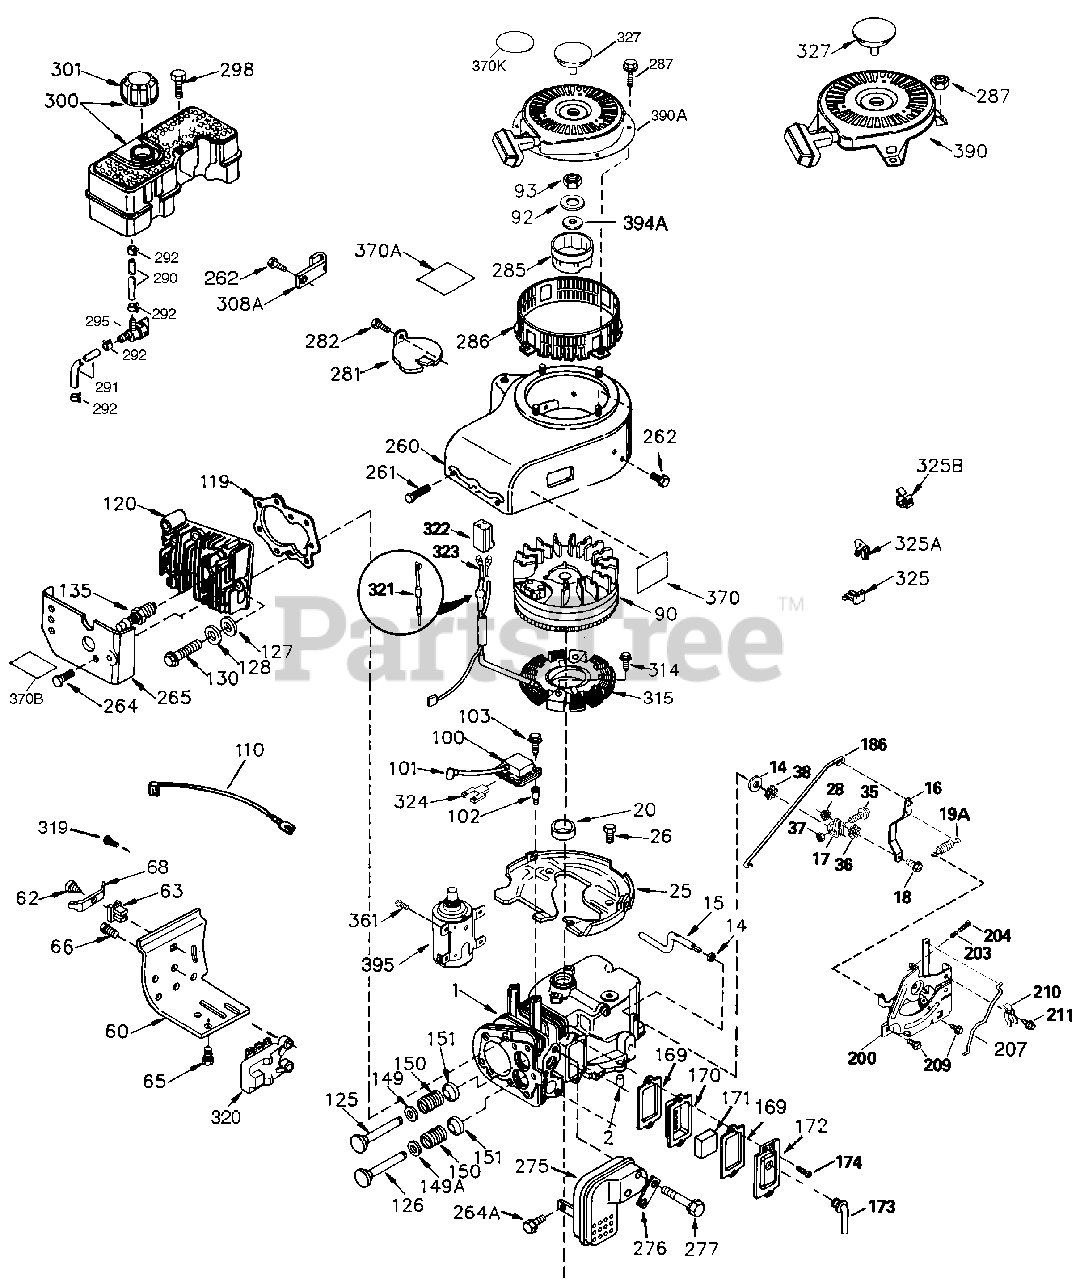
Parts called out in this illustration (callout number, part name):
1	"Cylinder (Incl. 2 & 20)
2	Dowel Pin
14	Flat Washer
15	Governor Rod
16	Governor Lever
17	Governor Lever Clamp
18	Screw, 8-32 x 5/16"
19A	Extension Spring
20	Oil Seal
25	Blower Housing Baffle (Incl. 325)
26	Screw, 1/4-20 x 5/8"
28	Lock Nut, 8-32
35	Screw, 10-32 x 3/4"
36	Lock Washer #8
37	Lock Nut, 10-32
38	Retaining Ring
60	Blower Housing Extension
64	Screw, 5/16-18 x 15/32"
65	Screw, 10-24 x 1/2"
90	Flywheel
92	Lock Washer
93	Flywheel Nut
100	Solid State Ignition
101	Spark Plug Cover
102	Solid State Mounting Stud
103	Screw, Torx T-15, 10-24 x 15/16"
110	Ground Wire
119	* Cylinder Head Gasket
120	Cylinder Head
125	Exhaust Valve (Std.)(Incl. 151)
125	Exhaust Valve (1/32" OS) (Incl. 151)
126	Intake Valve (Std.) (Incl. 151)
126	Intake Valve (1/32" OS) (Incl. 151)
128	Belleville Washer
130	Screw, 5/16-18 x 2"
135	Resistor Spark Plug - RJ17LM
149	Valve Spring Cap
149A	Valve Spring Cap
150	Valve Spring
151	Valve Spring Keeper
169	* Valve Cover Gasket
170	Breather Body
171	Breather Element
172	Valve Cover
173	Breather Tube
174	Screw, 10-24 x 1/2"
186	Governor Link
200	Control Bracket (Incl. 203,204 & 206)
203	Compression Spring
204	Screw, 5-40 x 7/16"
207	Throttle Link
209	Screw, 10-24 x 9/16"
260	Blower Housing
261	Screw, 5/16-18 x 3/4"
262	Screw, T-40, 5/16-24 x 21/32"
264A	Screw, 1/4-20 x 5/8"
265	Cylinder Head (Black)
275	Muffler
276	Locking Plate
277	Screw, 5/16-18 x 3-3/16"
281	Starter Bubble Cover
282	Screw, 8-32 x 3/8"
285	Starter Cup
287	Nut & Lock Washer 1/4-28
290	Fuel Line
292	Fuel Line Clamp
298	Screw, 10-32 x 35/64"
300	Fuel Tank (Incl. 292, 298 & 301)
301	Fuel Cap
325	Wire Clip
327	Starter Plug
355	Starter Handle
370	Lubrication Decal Not for use with 2- cycle engines.
370A	Decal - Important Lubrication - SAE 3
370B	Throttle Decal
390	Rewind Starter Note: This engine cou ld hav e been built with 590671 start er. Refer to the design of the rope p ulley strength ribs for part identifi cation. Individual starter parts do not interchange.
